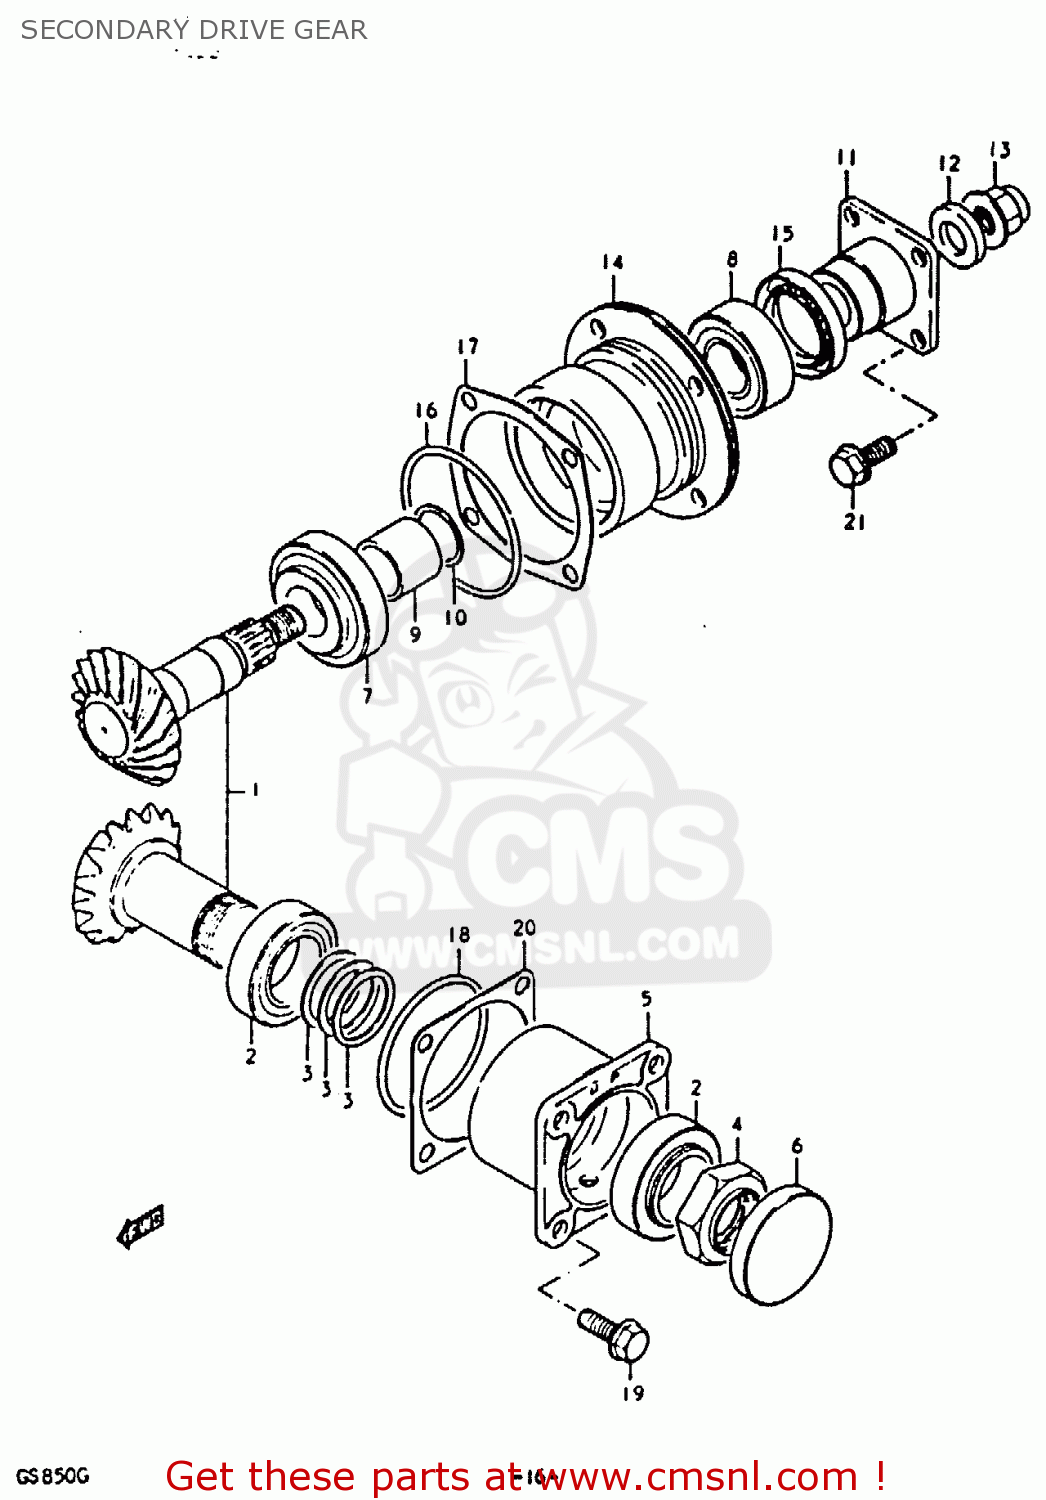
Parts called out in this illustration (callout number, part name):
1	SECONDARY GEAR SET
2	BEARING(32X58X17)
3	SHIM(32X38X2)
4	NUT
5	HOUSING,SECONDARY DRIVE
6	PLUG
7	TAPER,ROLLER BEARING
8	BEARING
9	SPACER (25.2X30X40)
10	SHIM (25X30X2
11	FLANGE,UNIVERSAL JOINT
12	WASHER(14X29X4)
13	NUT
14	HOUSING,SECONDARY DRIVE
15	SEAL,OIL(35X52X9)
16	O RING(D:3.1,ID:69.4)
17	SHIM,DRIVEN GEAR HOUSING
18	O RING(D:2.4,ID:62.6)
19	BOLT
20	SHIM,SECONDARY DRIVE
21	BOLT
